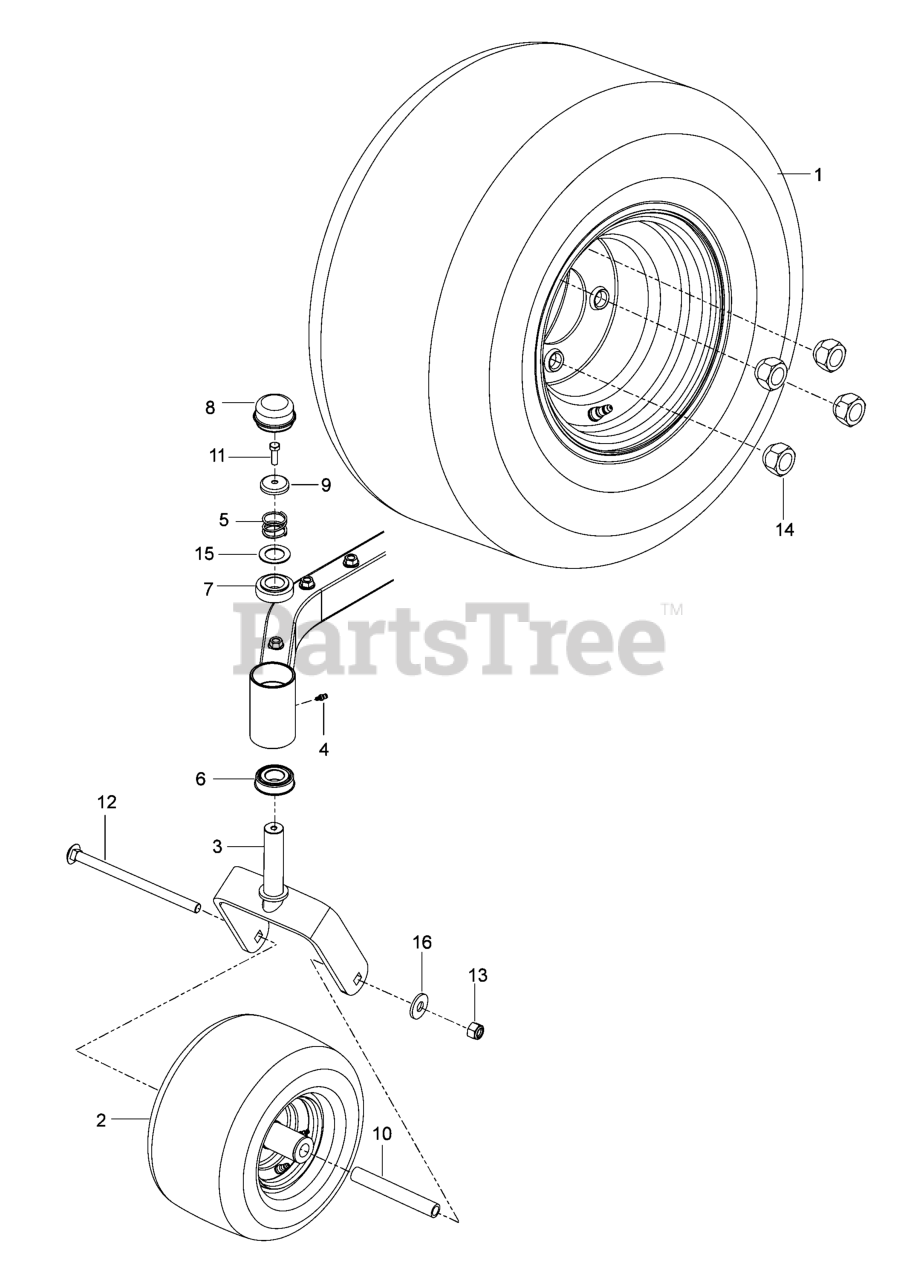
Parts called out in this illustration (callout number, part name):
1	WHEEL ASSEMBLY
2	WHEEL ASSEMBLY
3	YOKE, Caster
4	ZERK, Grease Fitting
6	BEARING, Flange
7	BUSHING, Caster
8	COVER, Dust
9	CAP, Plug
11	CAPSCREW, 5/16-18 X 1 W/ NYLON PATCH
12	BOLT, 1/2-13X7-1/2
13	LOCKNUT, 1/2-13 HEX CENTER LOCK
